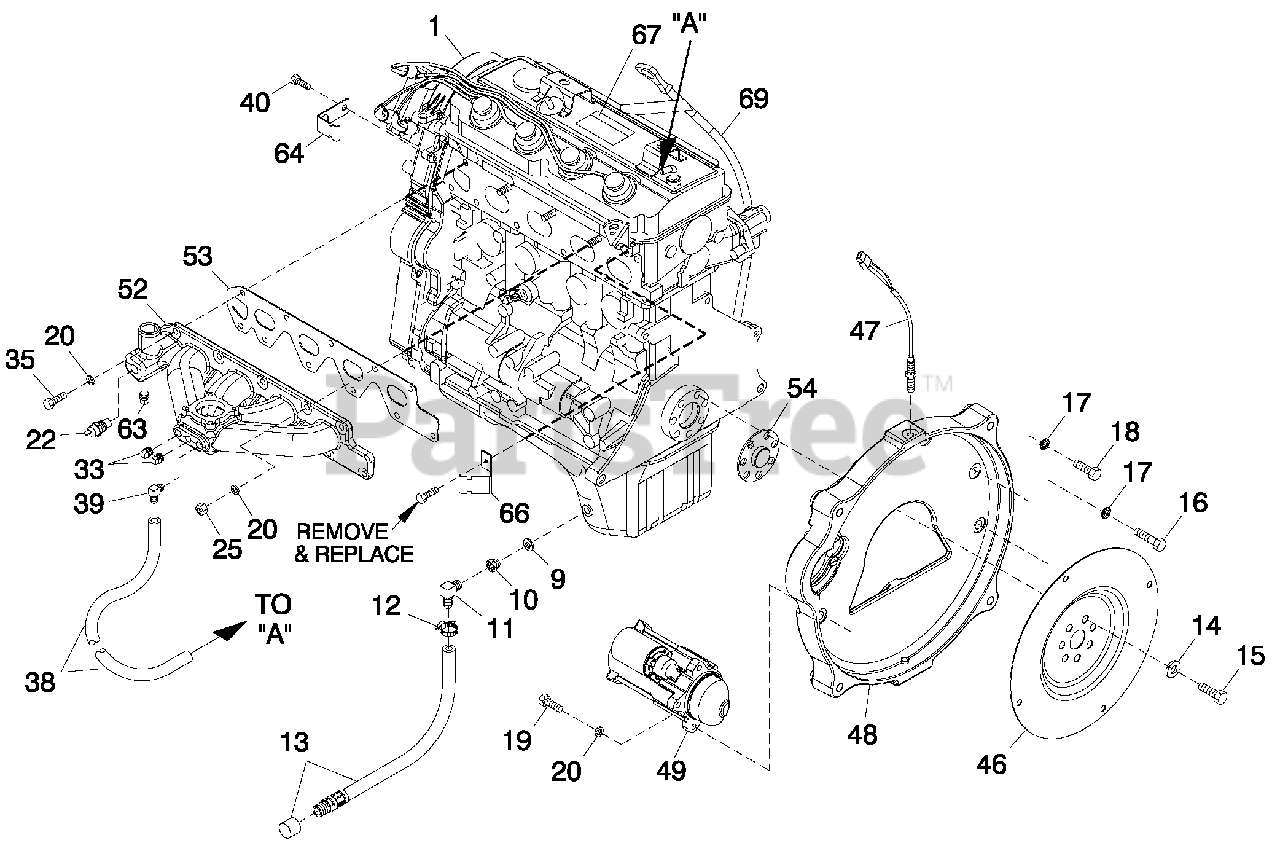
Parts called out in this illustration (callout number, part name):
1	ENGINE 2.4LG2 4G64CERT
2	WASHERLOCK M10
3	SCREW HHC M8-1.25X35G8.8
4	SCREW SHC M14-1.5 X 35 G10.9
5	ALTERNATOR DC W/O U T P U LLEY
6	SPACER DC ALTERNATOR P ULLEY
7	ADAPTOR 1/8 NPTF TO 1/8 BSPT
8	SWITCH OIL PRESS U RE 10 PSI 2 POL (R-PANEL)
9	WASHER NYLON .565
10	ADAPTER M14-1.50X 3/8 NPT
11	BARBED EL 90 3/8 NPT X 3/8
12	CLAMP HOSE .38-.87
13	HOSE DRAIN ASSY 28"
14	WASHER FLAT .531 ID X 1.062 OD
15	SCREW HHC M12-1.25X20G10.9
16	SCREW HHC M10-1.25 X 45 G8.8
17	WASHER SHAKEPROOF EXT 7/16 STL
18	SCREW HHC M10-1.25 X 30 G8.8
19	SCREW SHC M8-1.25 X 30 G12.9
20	WASHER LOCK M8-5/16
21	SCREW THF M6-1 X 16 N WA Z/JS
22	SWITCH HI-TEMP 245D X 3/8 NPT (R-PANEL)
23	WASHER FLAT 5/16-M8 ZINC
25	N UT HEX M8-1.25 G8 CLEAR ZINC
26	WASHER FLAT 3/8-M10 ZINC
27	N UT HEXM6X 1.0G8YELCHR
28	N UT HEX M10-1.25 G8YELCHR
29	SCREW SHC M8-1.25X25G12.9
30	WASHER LOCK M6-1/4
31	WASHER FLAT 1/4-M6 ZINC
32	SCREW HHC M6-1.0X 12 G8.8
33	PLUG STD PIPE 1/4 STEEL SQ HD
34	SCREW HHC M10-1.5X60 G8.8
35	SCREW HHC M8-1.25 X 25 G10.9
36	OIL FILTER G2 ENGINE
37	COIL PACK
38	HOSE 3/8 ID SINGLE BRAID (15" LG)
39	BARBED EL 90 1/4 NPT X 3/8
40	SCREW HHC M6-1.0X25G8.8
44	GASKET EXHAUST MANIFOLD
45	EXHAU ST MANIFOLD G2 (MACHINE) (25KW, 35KW & 45KW)
46	FLEX PLATE 2 POLE 2.4LG2
47	ASSY MAGPICKUP(3/8-24 MALE)
48	ADAPTER ENGINE 2.4L MACHINE
49	STARTER MOTOR 12V
50	CAM SENSOR PIN ASSY
51	COVER CAM GEARG2 REWORKED
52	MANIFOLD INTAKE (U SE HOSE 0G0816)
53	GASKET INTAKE MANIFOLD
54	SPACER 2.4L G2 FLEX PLATE
55	SHIELD HEATG2
56	SHIELD HEATSML
57	BRACKET COIL PACK
59	ADAPTER 2.4L CRANKSHAFT MACH
60	POLY V-BELT G2 (3600 RPM)
61	P U LLEY DC ALTERNATOR (3600 RPM)
62	SCREW HHC M6-1.0 X 35 G8.8 BLK
63	PL U G STD PIPE 3/8 STEEL SQ HD
64	BRACKET, SIGNAL CONDITIONER
65	SCREW HHC M8-1.25X70 G8.8
66	BRACKET SIGNAL CONDITONER
67	DECAL EMISSION CTRL INFO 2.4L
69	ROD ASSY OIL LEVEL GA U GE
70	O-RING SIZE 9.0MM X 2.0MM NITR
71	CABLE, SPARK PLU G, NO.1
72	CABLE, SPARK PLU G, NO.2
73	CABLE, SPARK PLU G, NO.3
74	CABLE, SPARK PLU G, NO.4
75	PLUG TAPER
